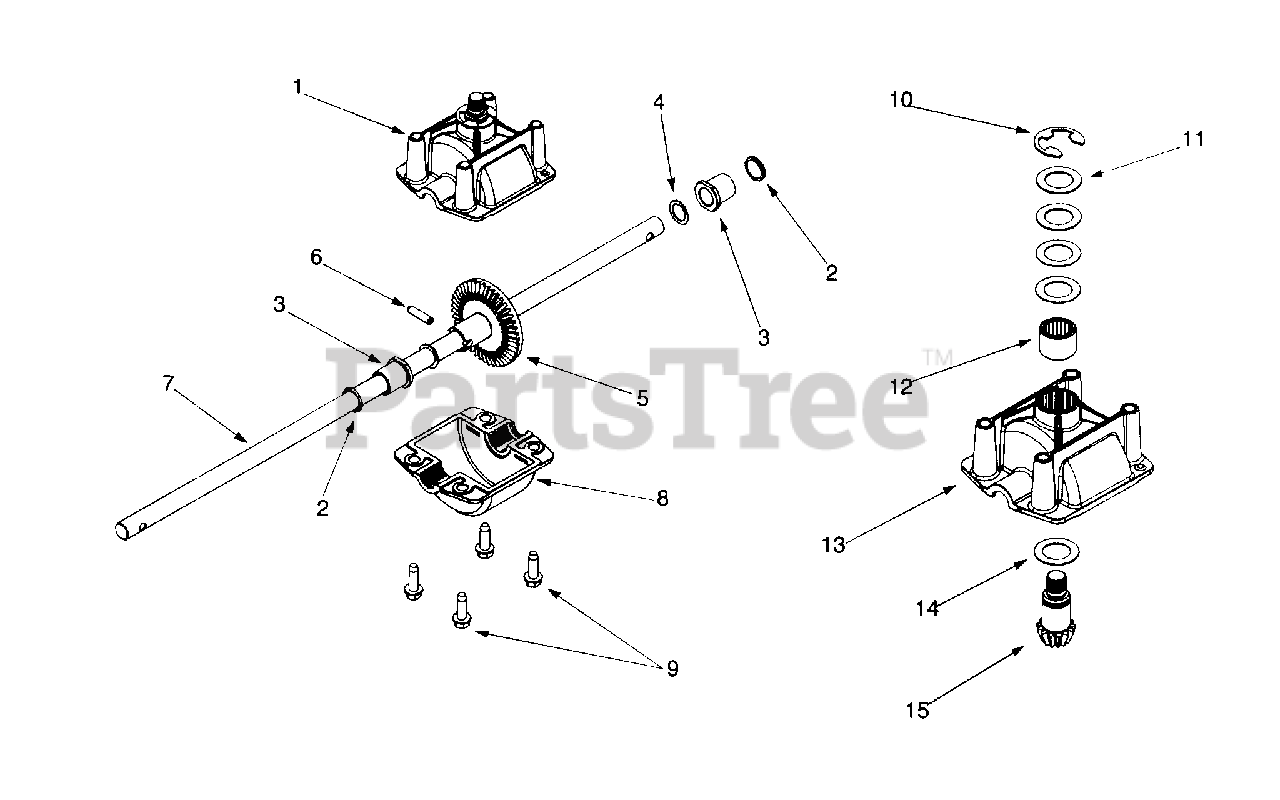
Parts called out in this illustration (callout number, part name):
1	Upper Housing Assembly
2	Oil Seal .500 ID x .687 OD
3	Flange Bearing .503 ID x .689 OD
4	Flat Washer .504 ID x .700 OD x .030
5	Bevel Gear 44T
6	Roll Pin
7	Output Shaft
8	Lower Housing
9	Hex Washer Screw 1/4-20 x .75
10	E-Ring .750
11	Flat Washer .625 ID x 1.0 OD x .030
12	Needle Bearing .625 x .813
13	Upper Housing
14	Flat Washer .625 ID x 1.0 OD x .030
15	Input Shaft
